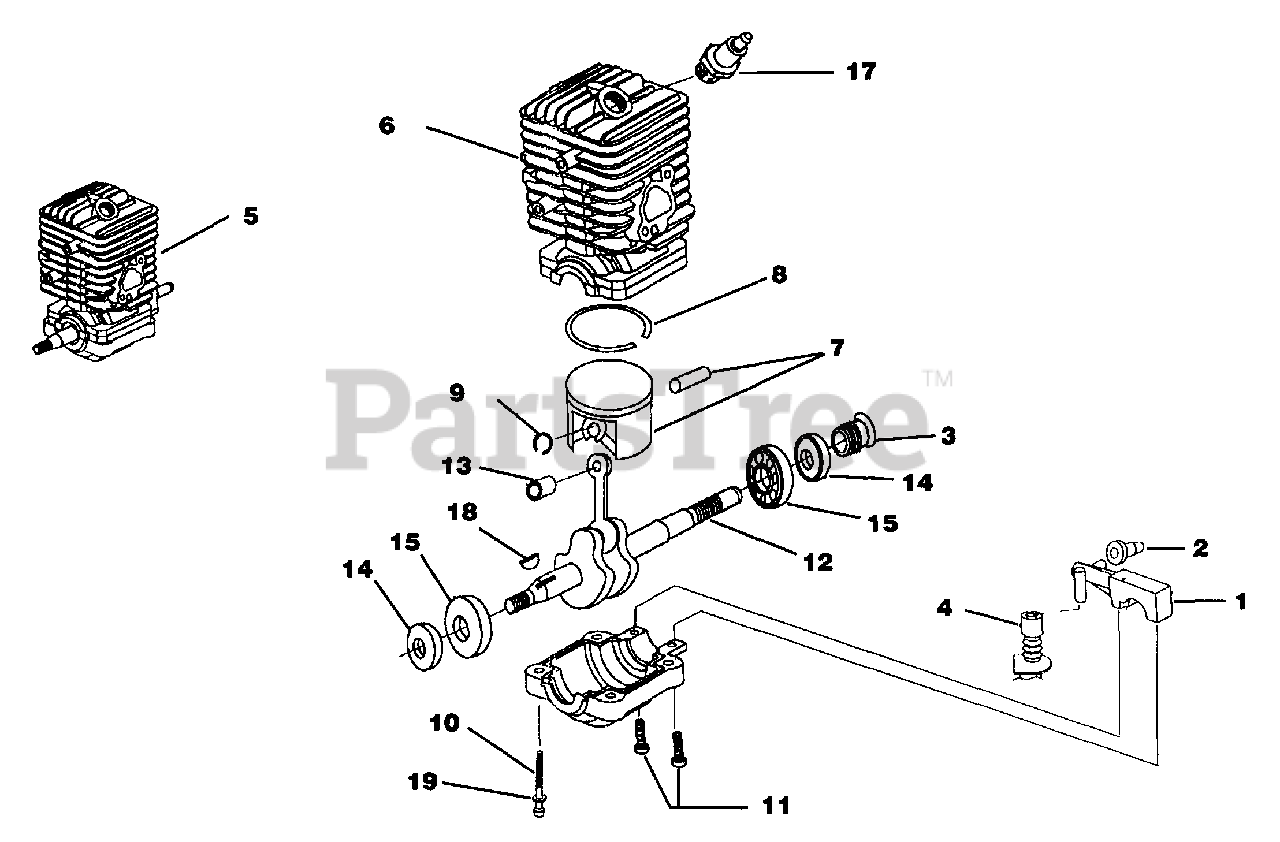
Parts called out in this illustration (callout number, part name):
1	Oil Pump Kit
2	Grommet, Oil Outlet
3	Left Hand Worm
4	Tube, Oil Intake
5	Short Block, Complete
6	Cylinder Kit
7	Piston & Pin
8	Piston Ring
9	Ring, Retaining
10	Screw, Cap-Socket Hd. (10-24 x 2")
11	Screw, Pan Hd. (8-16 x 5/8")
12	Crankshaft & Rod Assembly
13	Bearing, Needle
14	Shaft Seal
15	Bearing & Case
17	Spark Plug
18	Woodruff Key
19	Washer
